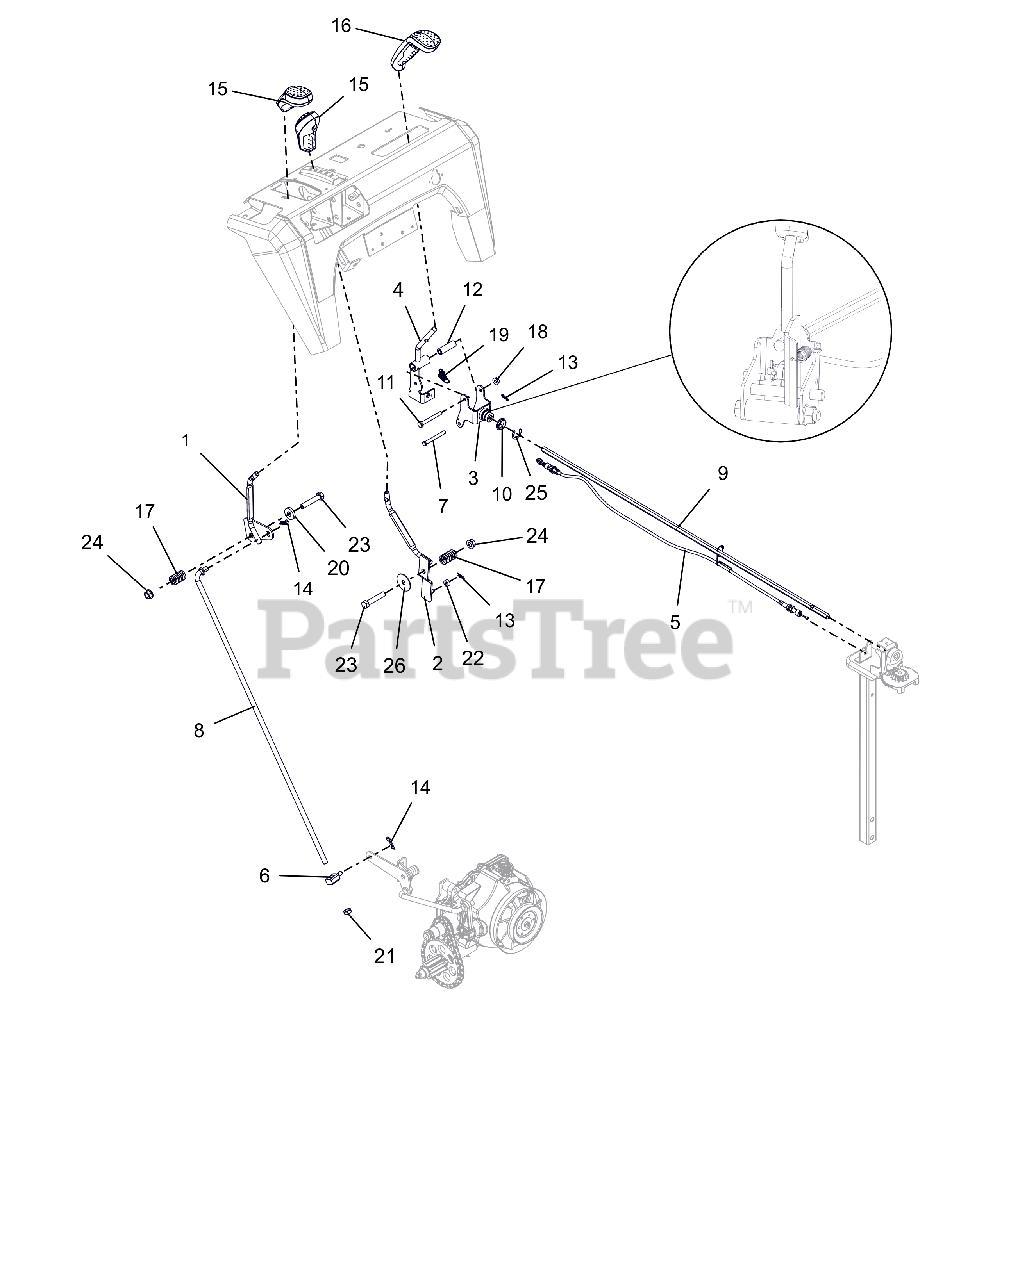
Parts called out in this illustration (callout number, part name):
1	WELDMENT,LG DASH SPEED CONTROL
2	WELDMENT,LG DASH DEFL CONTROL
3	WELDMENT, CONTROL BRACKET
4	WELDMENT, CONTROL LEVER
5	CABLE, CHUTE LOCK, PRO
6	PIVOT,SHIFT ROD .375-16(TRUNN)
7	PIN, CLEVIS - .25 X 2.25 ZCC
8	ROD, SHIFT-PRO
9	ROD, HEX - CHUTE ROTATION
10	BUSHING, POLYLINER-.75 SNAPIN
11	BLT,HEX .25-20X2.25 G5 ZCC
12	BSHG, SLV .265X.505X1.665
13	PIN, HAIR #178 .06X.77 ZCC
14	PIN, HAIR #213 .08X1.19 ZCC
15	KNOB, CONTROL, DASH
16	HANDLE, QUICK TURN, ASM
17	SG-COMP .125X.781X1.250
18	NUT-LK-CTR-FLG .25-20 ZC120
19	SPRING-EXT .047X.438X1.45
20	WSHR, FLT .406X1.00X.188 ZCC
21	NUT-JAM .375-16 G2 ZCC
22	BSHG-SLV .265X.500X.219
23	BLT,HEX .38-16X2.00 G5 ZCC
24	NUT-LK-TOP-FLG .38-16 ZC120
25	E-RING .750X.050
26	WSHR,FLT .380X1.50X.062 ZCC
